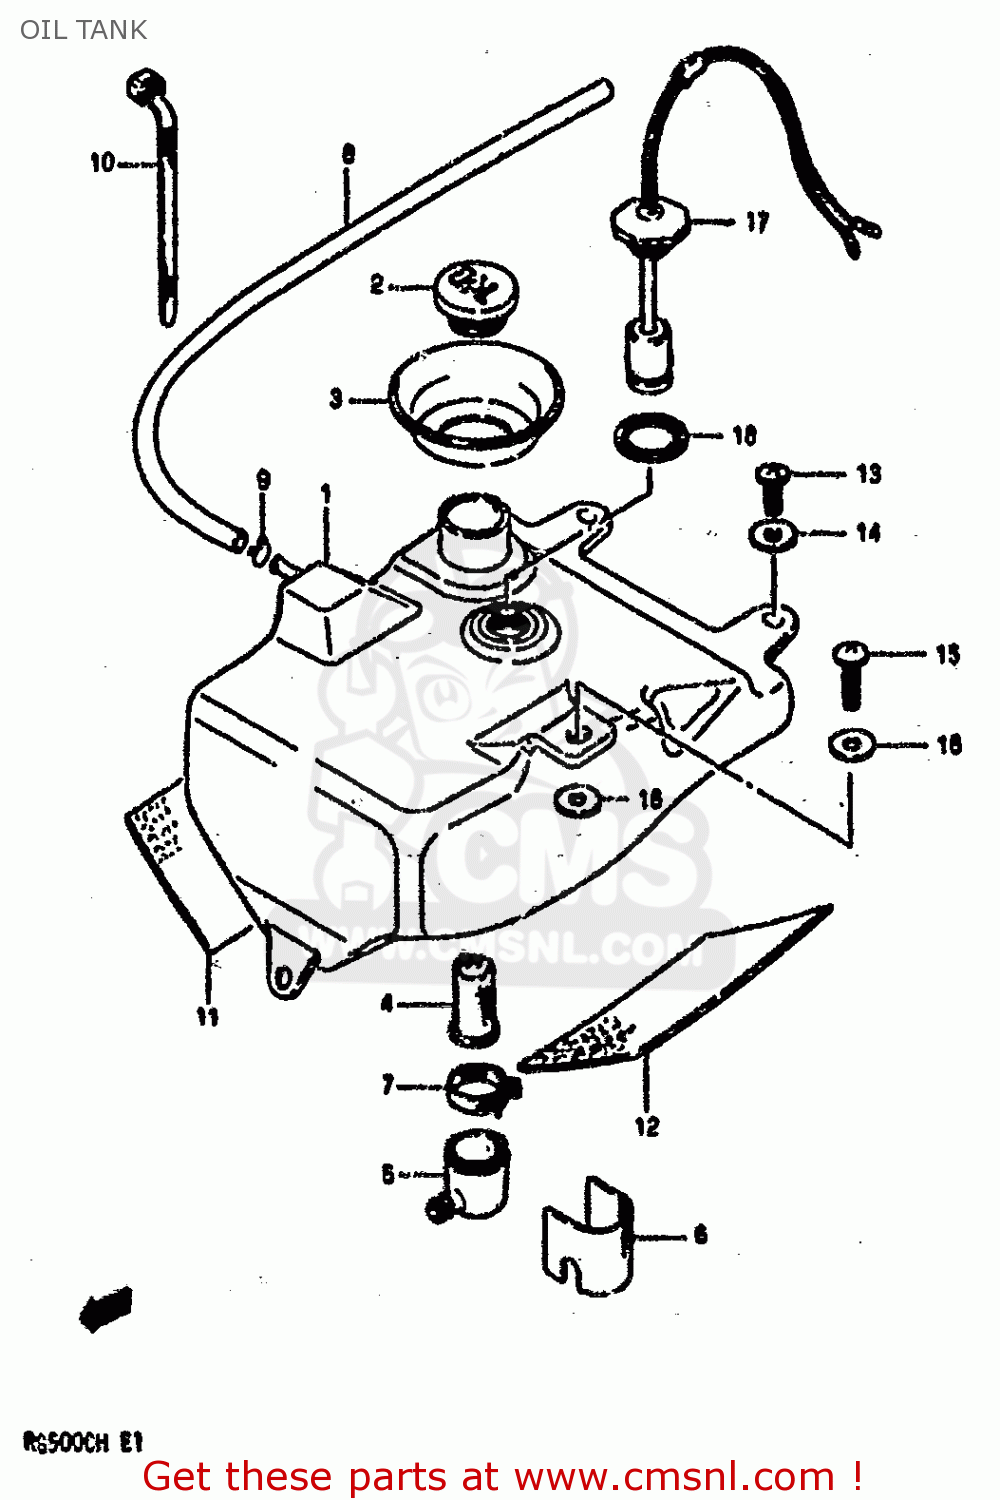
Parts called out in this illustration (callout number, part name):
1	TANK,OIL
2	CAP,OIL TANK
3	RUBBER,OIL TANK INLET
4	BODY,OIL FILTER
5	BODY,OIL OUTLET
6	HEAT SHIELD,OUTLET
7	CLIP
8	HOSE,BREATHER
9	CLIP
10	CLAMP
11	HEAT SHIELD,OIL TANK RH
12	HEAT SHIELD,OIL TANK LH
13	SCREW
14	WASHER
15	SCREW
16	WASHER
17	SWITCH ASSY,OIL LEVEL
18	GASKET (NAS)
